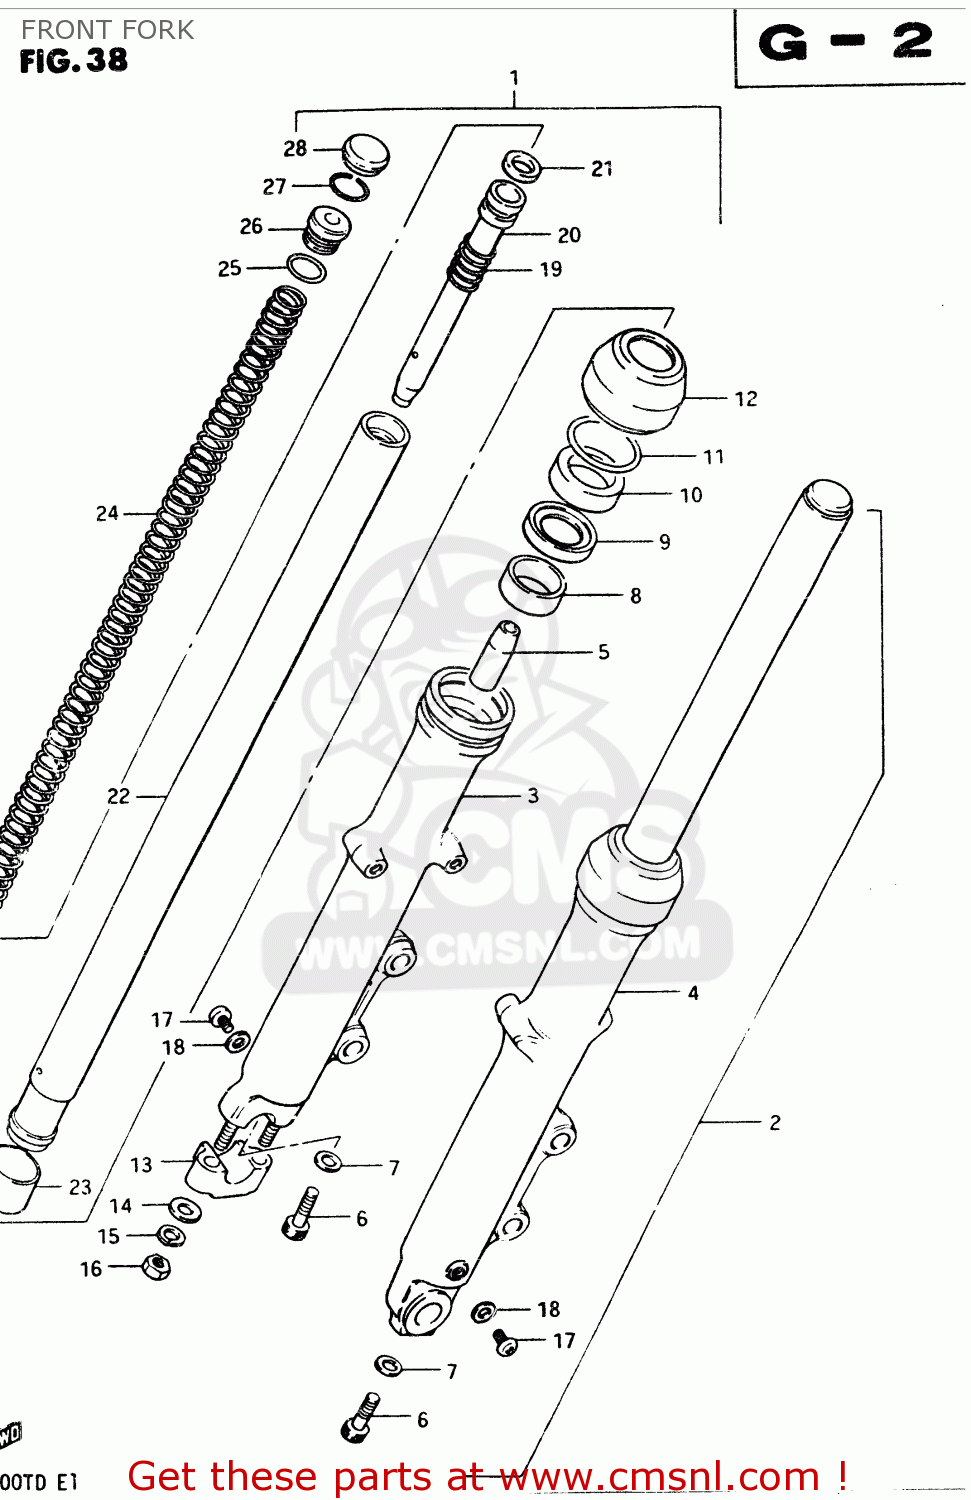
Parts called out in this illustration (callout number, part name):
1	DUMPER ASSY, RH
2	DUMPER ASSY, LH
3	TUBE,FORK,OUTER,RIGHT
4	TUBE,FORK,LEFT,OUTER
5	PIECE,OIL LOCK
6	BOLT(8X27)
7	GASKET (NAS)
8	BUSH,GUIDE
9	SPACER,OIL SEAL
10	OIL SEAL,FRONT FORK
11	RING,OIL SEAL STOPPER
12	DUST SEAL
13	HOLDER,AXLE
14	WASHER
15	LOCK WASHER
16	NUT (8MM)
17	SCREW 4X6
18	GASKET (NAS)
19	SPRING,REBOUND
20	CYLINDER,FRONT FORK
21	RING,PISTON
22	TUBE,FORK,INNER
23	BUSH
24	SPRING
25	O RING
26	SEAT,SPRING
27	RING,STOPPER
28	CAP,FRONT FORK
